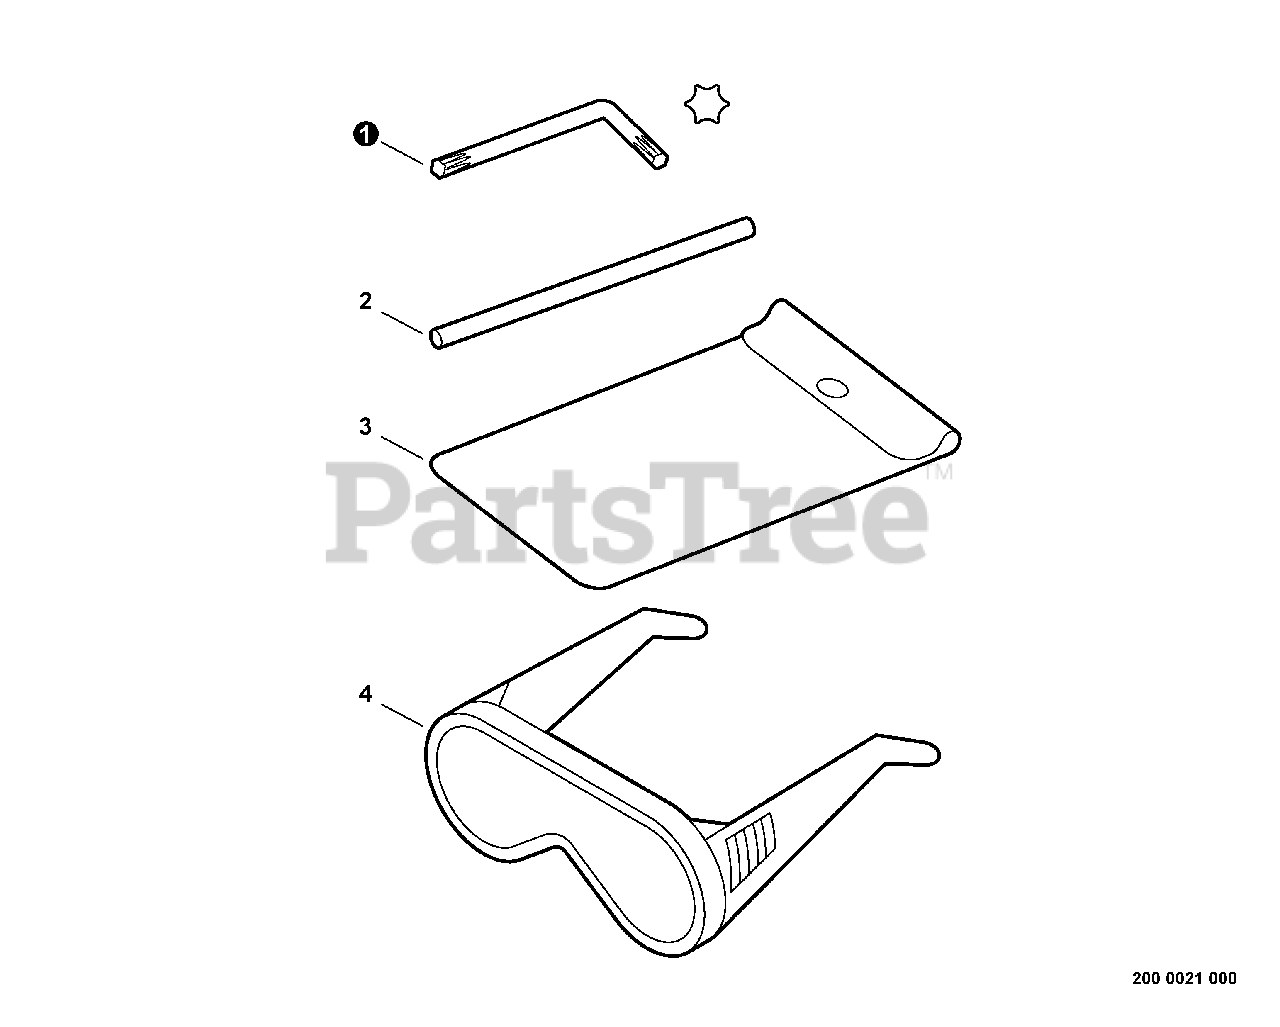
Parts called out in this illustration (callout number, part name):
1	WRENCH, T27 80×30
2	TOOL, LOCKING 5×120 MM
3	BAG, TOOL
4	GLASSES, SAFETY
